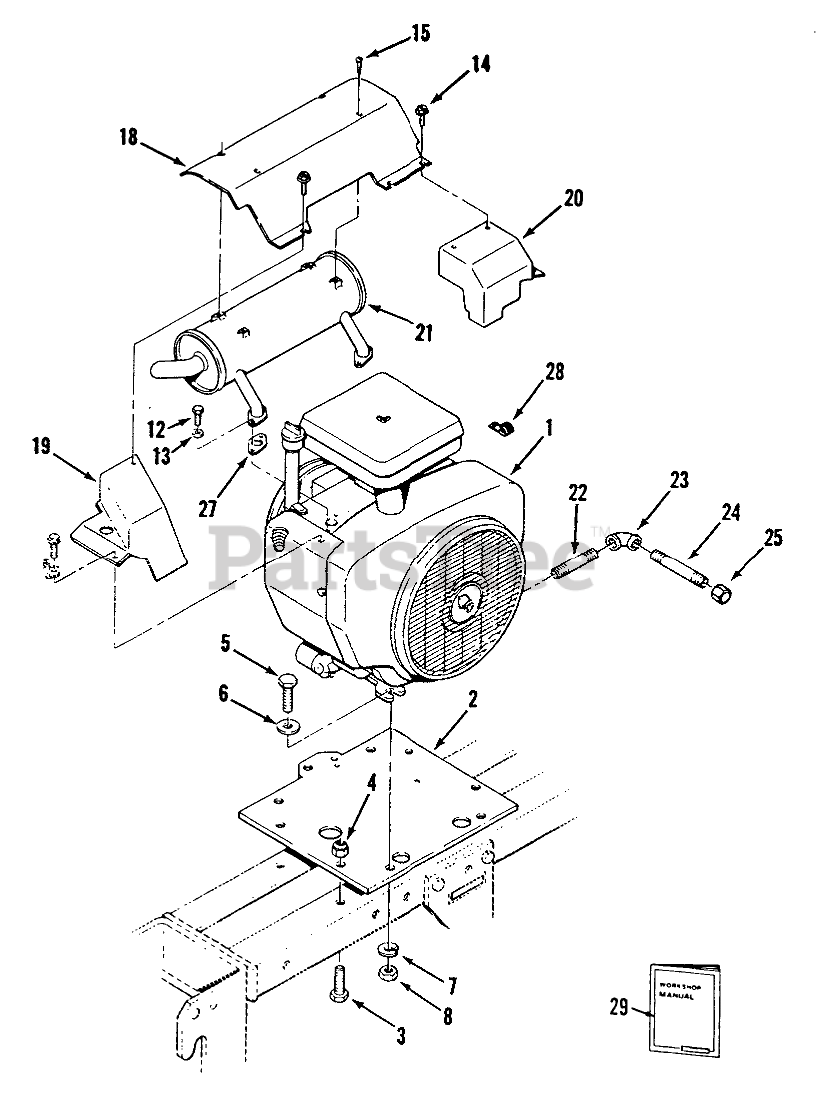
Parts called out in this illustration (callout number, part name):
2	PLATE-ENGINE B
3	BOLT
4	NUT
5	BOLT
6	Washer
7	LOCKWASHER
8	Nut
12	Bolt
13	Lockwasher
14	HEX WASHER HD SCREW
15	Screw
18	Air Deflector
19	LH Exhaust Cover
20	RH Exhaust Cover
21	MUFFLER-EXHAUST
22	Pipe
23	ELBOW 3/8 90 DEG
24	PIPE-NIPPLE 3/8 X 4"
25	Cap
27	Exhaust Gasket
28	J-CLIP
29	Manual-Toro Power Plus Service
